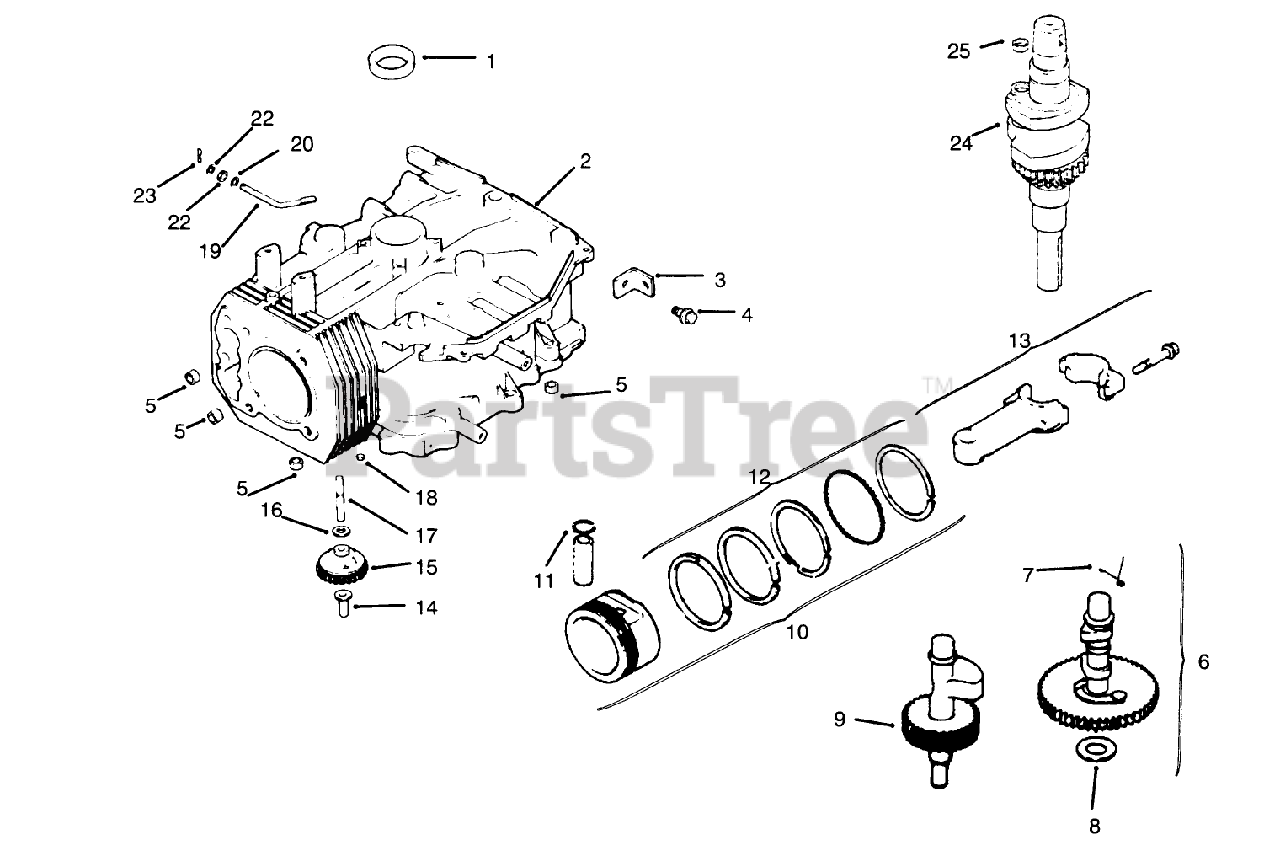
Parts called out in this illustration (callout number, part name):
1	Seal-Crankshaft
2	Short Block
3	Strap-Lifting
4	Screw
5	Pin-Dowel
6	Camshaft Assembly
7	Spring-Actuating
8	Shim-Camshaft
9	Shaft Balance
10	Set Piston w/Ring STD
11	Retainer-Piston Pin
12	Ring Set STD
13	Rod Connecting STD
14	Pin-Governor
15	Gear, governor
16	Washer
17	Shaft-Gear, Governor
18	Plug
19	Shaft-Governor Cross
20	Washer
21	Seal-Cross Shaft
23	Pin-Hitch
24	Crankshaft ASM
25	Plug-Cup
